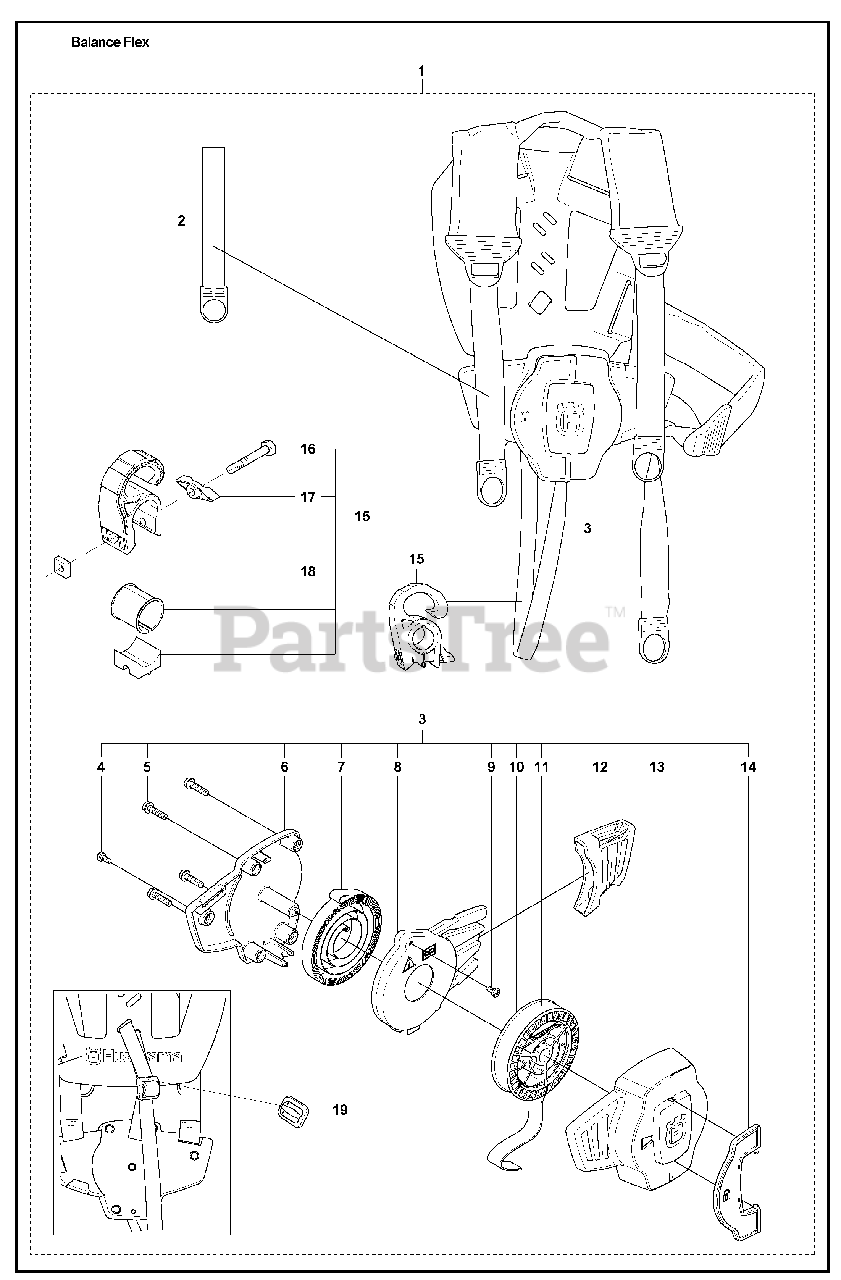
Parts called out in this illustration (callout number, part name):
1	BALANCE FLEX HARNESS
3	BALANCE FLEX HARNESS
5	SCREW
6	Back Plate
7	SPRING COIL
8	SPRING CASSETTE
10	STARTER PULLEY
12	Front Piece Brace
14	Locking Lever Button
15	ACCESSORY BAG
